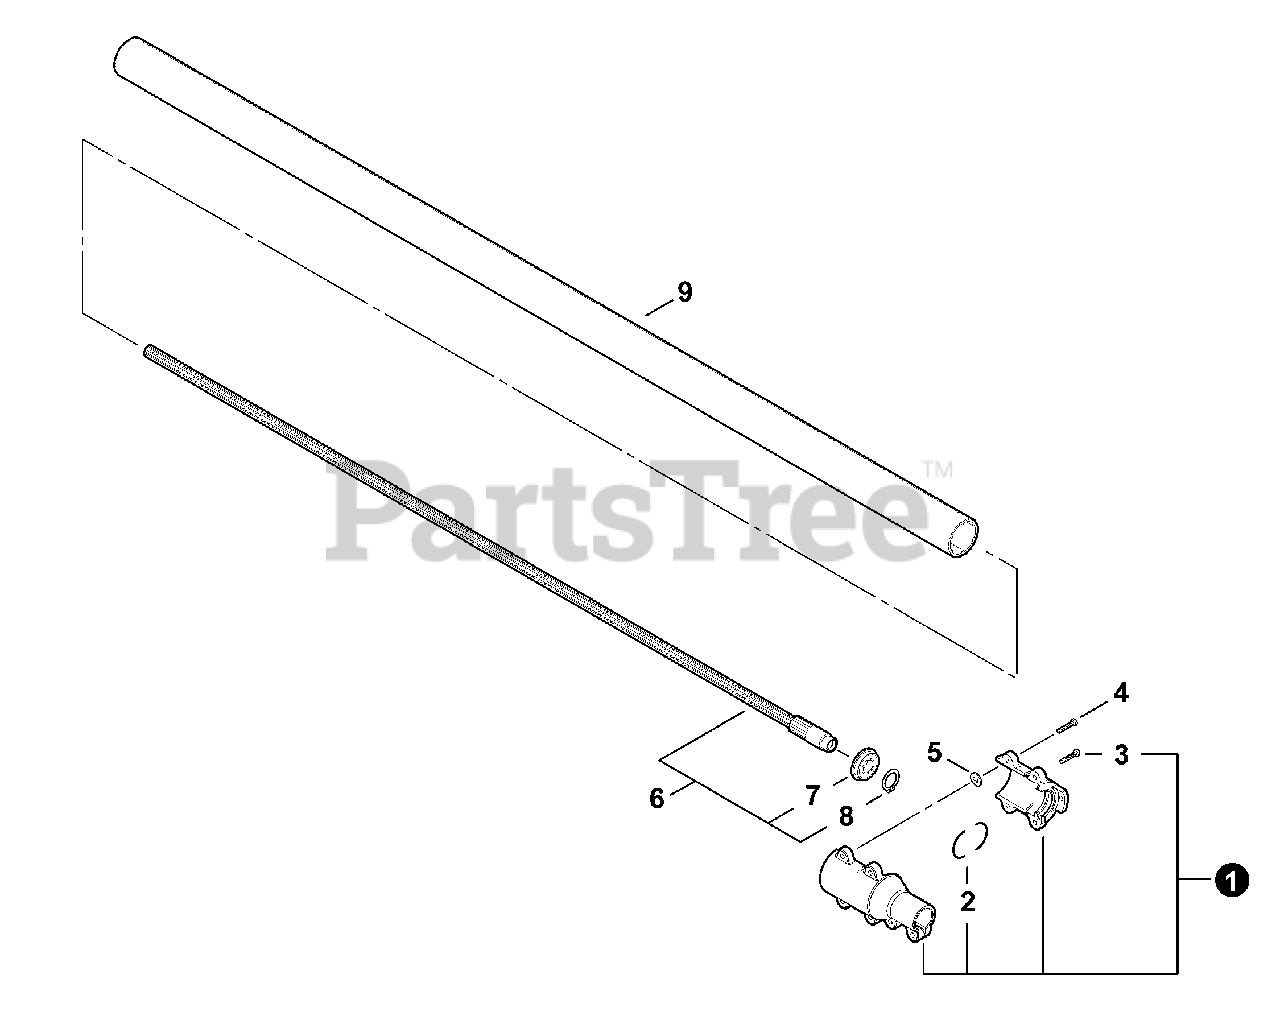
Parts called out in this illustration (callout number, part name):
1	COUPLING ASSY, LOWER
2	CUSHION
3	BOLT, TORX 5×20
4	BOLT, TORX 5×20
5	WASHER 5
6	DRIVESHAFT ASSY, LOWER
7	BEARING, BALL 15×32×9
8	RING, RETAINING
9	PIPE, MAIN - ORANGE
